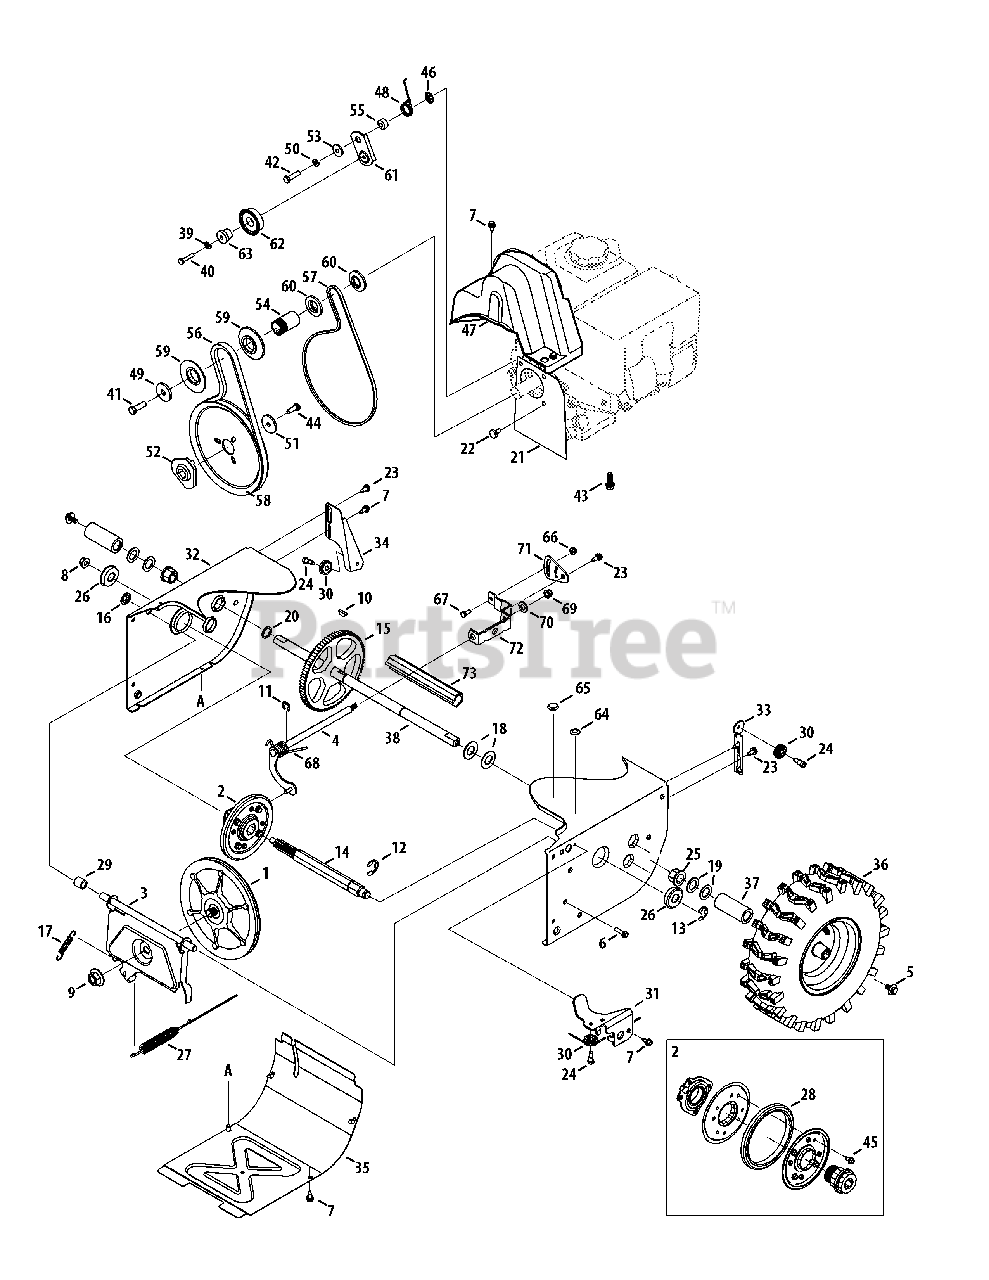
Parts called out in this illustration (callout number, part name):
1	Disc Assembly, Friction Wheel
2	Friction Wheel Assembly, 5.5 OD
3	Support Bracket, Friction Wheel
4	Shift Assembly, Rod
5	Screw, 5/16-24, .750, Gr5
6	Screw, 1/4-20, 1.000
7	Screw, 1/4-20 x .625
8	Nut, Flange Lock, 3/8-16, Nylon
9	Nut, Flange, 5/8-18
10	Key, Hi Pro, 3/16 x 3/4 Dia.
11	E-ring, .500 Dia.
12	E-ring, Retaining, .875 Dia.
13	E-ring, .750 Dia.
14	Hex Shaft, .8125, 7-Tooth
15	Gear, 80-Tooth
16	Speed Nut, .500
17	Extension Spring
18	Washer, Flat, .760 x 1.490 x .060
19	Washer, Flat, .793 x 1.24 x .060
20	Washer, Flat, .75 x 1.00 x .060
21	Plate, Cover
22	Shoulder Screw
23	Screw, Shoulder, .37 x .105, 1/4-20
24	Screw, 1/4-28, .375
25	Bearing, Hex Flange x .75 ID
26	Bearing, Ball, 17 x 40 x 12
27	Clutch Cable, Wheel, 44.95"
28	Rubber, Friction Wheel, 5.5 OD
29	Spacer, .508 ID x .75 OD x .68
30	Roller, Cable
31	Front Guide Bracket, Auger Cable
32	Frame
33	Guide Bracket, Auger Cable
34	Guide Bracket, Drive Cable
35	Cover, Frame
36	LH Wheel Assembly
36	RH Wheel Assembly
37	Spacer, 1.25 x .75 x 3.0
38	Axle, .75 x 22"
39	Washer, Lock, 1/4
40	Hex Screw, 1/4-20, 1.25, Gr5
41	Hex Screw, 3/8-24, 1.25, Gr8
42	Hex Screw, 5/16-24, 1.25, Gr5
43	Screw, Sems, 3/8-16, 1.00
44	Hex Screw, 5/16-24, .875, Gr8
45	Screw, 5/16-18 x .750
46	Nut, Push-on, .25 Dia.
47	Cover, Belt
48	Spring, Torsion, .850 ID x .354
49	Washer, Flat, .45 x 1.5 x .172
50	Washer, Lock .3125
51	Washer, Flat, .34 x 1.50 x .150
52	Pulley, Adapter, .75 Dia.
53	Spacer, Shoulder, .317 x .50 x .102
54	Spacer, .875 ID x 1.185 OD
55	Spacer, .340 x .750 x .360
56	Belt, Auger Drive
57	Belt, Wheel Drive
58	Pulley, Auger Drive, 8.1 x .5
59	Pulley, Half, V x 2.600 OD
60	Pulley, Half, 3/8-V x 1.7160 OD
61	Idler Bracket, Wheel Drive
62	Idler Pulley Assembly
63	Spacer, Shoulder, .26 x .79 x .538
64	Plug, 3/8 ID
65	Plug, 1/2 ID
66	Nut, Flange Lock, 1/4-20, Nylon
67	Hex Screw, 1/4-20, .620, Gr5
68	Spring, Torsion, .750 ID x .968
69	Nut, Flange Lock, 5/16-18, Nylon
70	Wash., Flat, .469 x .875 x .105
71	Pivot Bracket, Speed Selector
72	Shift Bracket, Speed Selector
73	Spacer, Axle
